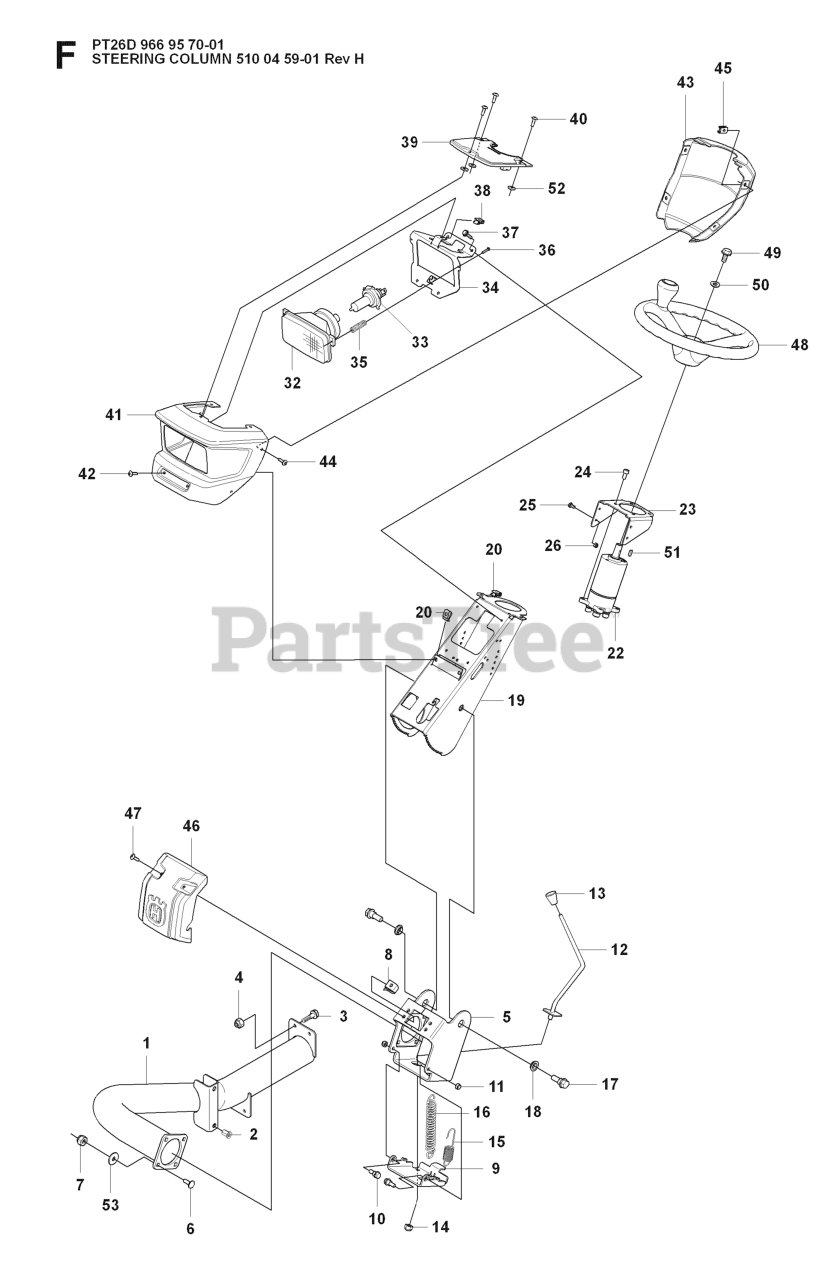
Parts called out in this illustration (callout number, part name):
4	LOCKNUT M8
7	LOCKNUT M8
11	LOCKNUT M8
16	DRAW SPRING L=108
25	BOLT FLANGE - M6X20
26	LOCKNUT M6
49	SCREW EHHFM
53	WASHER BRB 8.4X17
